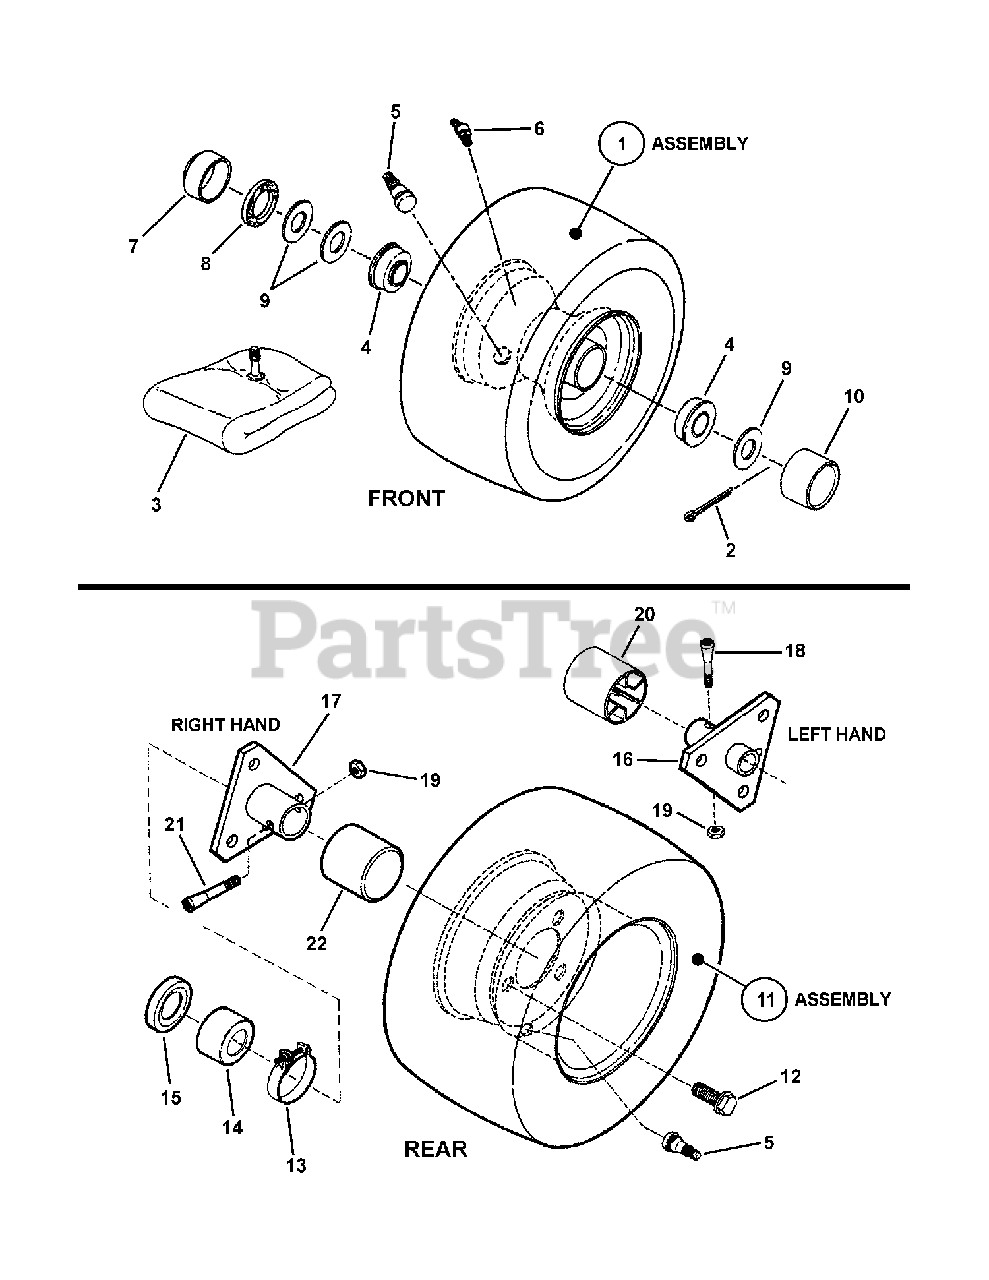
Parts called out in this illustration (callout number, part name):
1	ASSEMBLY, Front Tire & Rim (11.0") (Complete)
2	COTTER PIN, 5/32 x 1"
3	INNER TUBE, (For 4.10/3.50 x 4 Tire)
4	BALL BEARING, Flange (3/4" I.D.)
5	VALVE STEM, Snap In
6	LUBE Fitting
7	CAP, Dust
8	SEAL, Felt
9	WASHER, .77 x 1.13 x .06 Flat
10	HUB CAP
11	ASSEMBLY, Rear Tire & Rim
12	BOLT, 1/2-20 x 3/4" Lug, GR 5
13	CLAMP, Right Hand (for 2" Hose)
14	CAP, Seal RH 1.0" ID x 1.67" OD (8 & 10 HP)
15	SEAL, 1.22" ID x 1.875" OD
16	HUB, Rear Wheel L. H. (Weldment)
17	HUB, Rear Wheel R. H. (Weldment)
18	AXLE BOLT, 5/16-24 x 1-5/8" Tapered (Left Hand)
19	NUT, Wheel Bolt 5/16-24 Hex Center Lock
20	HUBCAP, L. H. (Long Axle)
21	WHEEL BOLT, 5/16-24 x 2" Tapered (Right Hand)
22	HUBCAP
